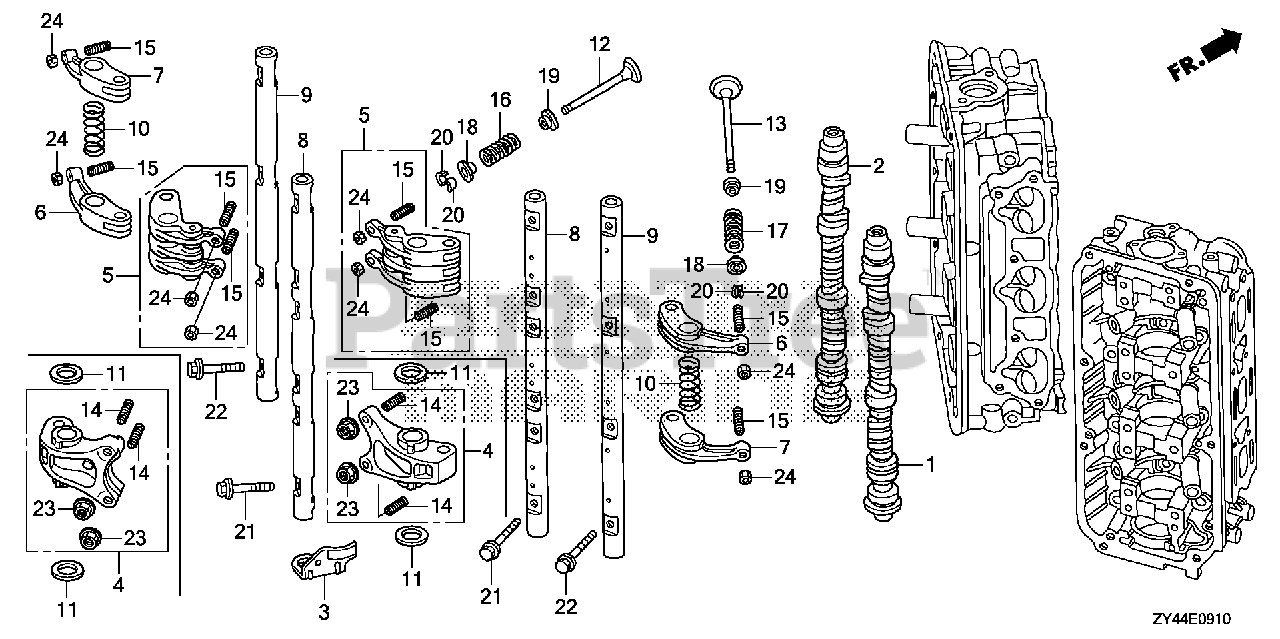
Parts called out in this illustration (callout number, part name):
1	CAMSHAFT, R.
2	CAMSHAFT, L.
3	ARM, FUEL PUMP ROCKER
5	ARM ASSY., IN. ROCKER
6	ARM A, EX. ROCKER
7	ARM B, EX. ROCKER
8	SHAFT, IN. ROCKER ARM
9	SHAFT, EX. ROCKER ARM
10	SPRING, ROCKER ARM
12	VALVE, IN.
13	VALVE, EX.
15	SCREW, TAPPET ADJUSTING
16	SPRING, IN. VALVE (GRAY) (ASSOCIATED SPRING)
17	SPRING, EX. VALVE (YEL/GRN) (ASSOCIATE)
18	RETAINER, VALVE SPRING
19	SEAT, VALVE SPRING
20	COTTER, VALVE (FUJI VALVE)
21	BOLT, FLANGE (8X30)
22	BOLT, FLANGE (8X40)
24	NUT, TAPPET ADJUSTING
